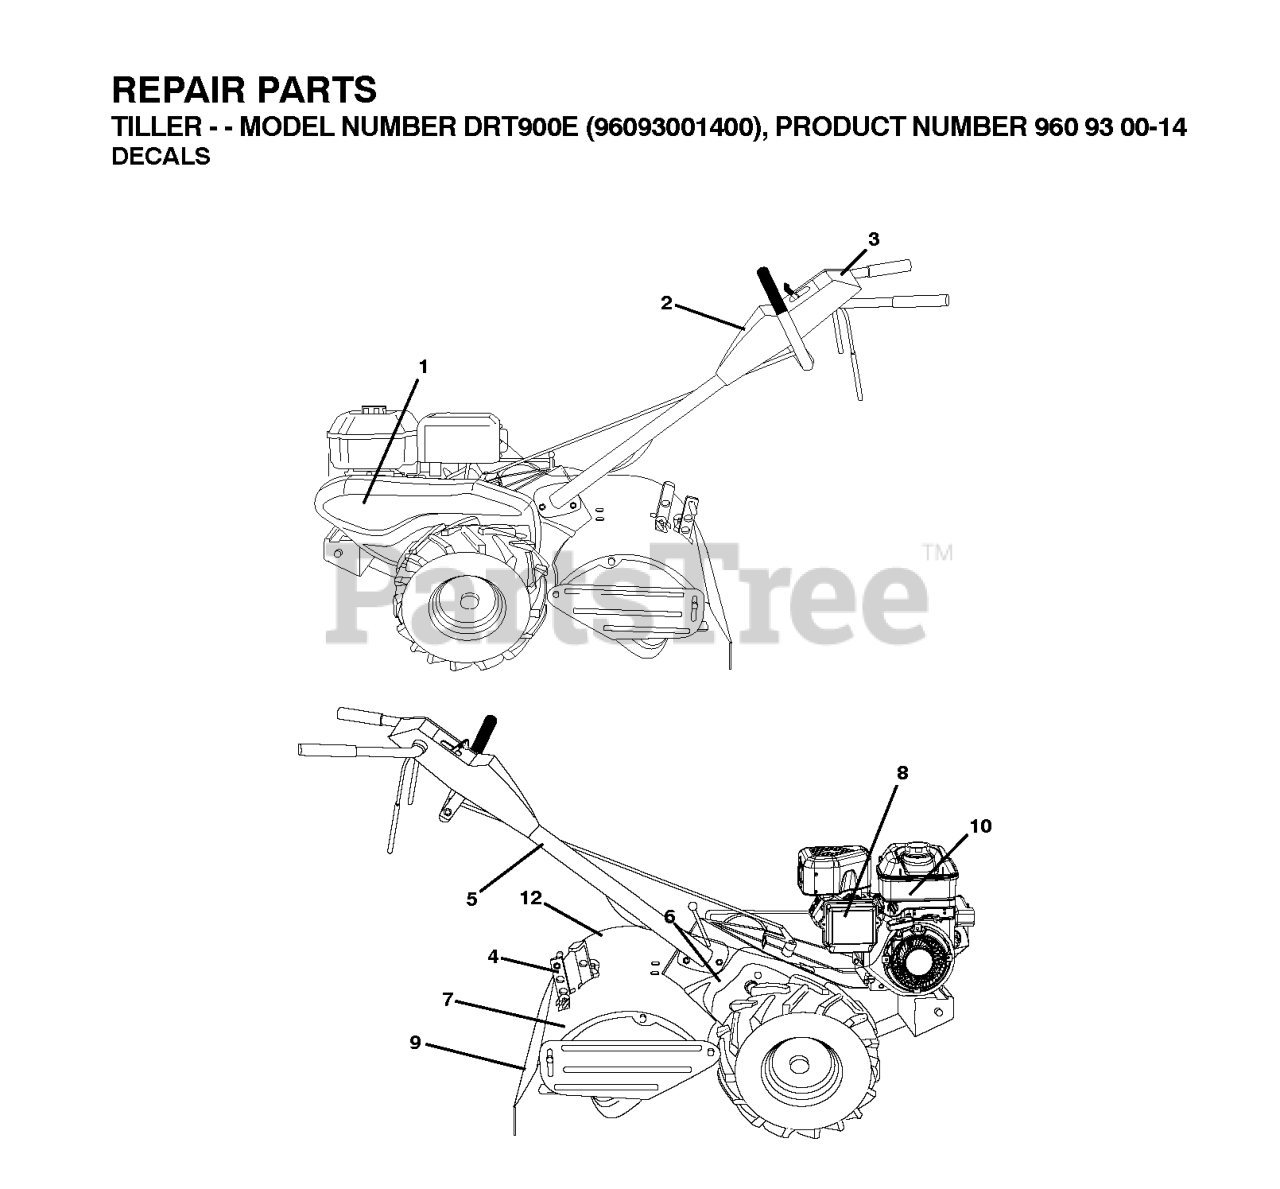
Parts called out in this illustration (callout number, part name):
1	RP.DECAL.BADGE.170MM.TEXTLOGO
4	DECAL.SHIELD.TN.DRT17.HUSQ
5	DECAL TI (2 2)
6	DECAL.SHIFT.INDICATOR.DRT
7	DECAL.REVERSE.HUSQ.TILLER
8	DECAL.B&S.900.A/S.C (279005)
9	DECAL.DRT.WARN.ENG/F
10	DECAL.B&S.900.TANK.REF.276991
12	DECAL.FOWARD.HUSQ.TILLER
